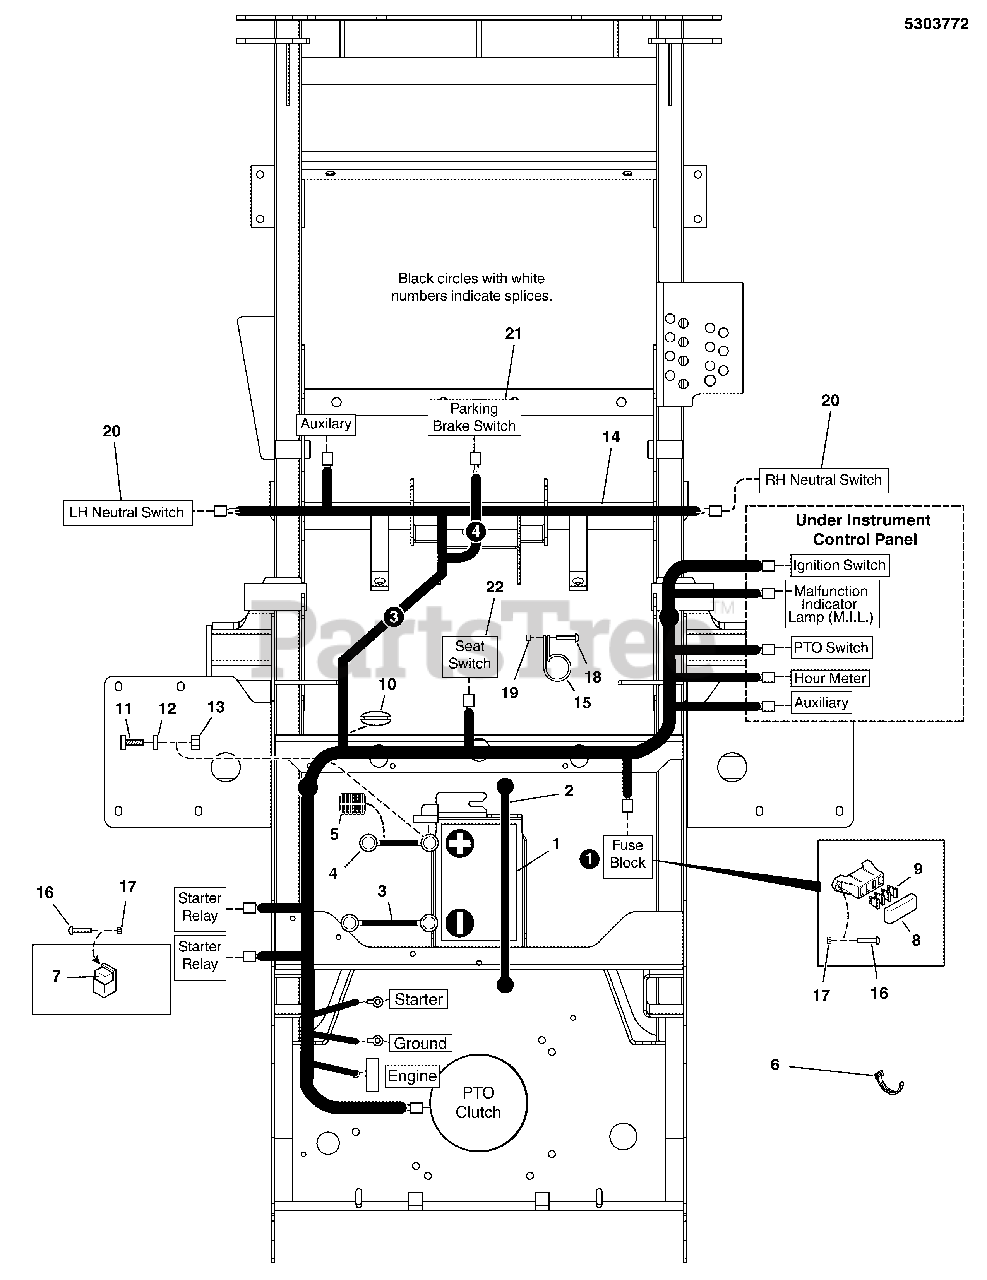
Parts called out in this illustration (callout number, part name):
1	BATTERY, WET ( BCIU1, 350 CCA)
2	STRAP-BLACK RUBB
3	BATTERY CABLE, NEG, 14, 5/16-13/32
4	BATTERY CABLE, POS, 22, 1/4-5/16
5	WIRE LOOM, 3/8 ID X 16 IN
6	TIE, SELF-LOCKING, 12"
7	RELAY, 12V, 40A
8	COVER, VINYL FUSEBLOCK
9	FUSE, ATO, 20 AMP
9	FUSE, ATO-15 (15 AMP)
10	GROMMET, 1-1/2" ID FOR 1/4" METAL
11	BOLT, 1/4-20 X 3/4 GD5 CZ
12	WASHER, 1/4 SAE
13	NUT, 1/4-20 HEX SERR. FLANGE
14	WIRE HARNESS, 28HP B&S EFI
15	CLAMP, VINYL INSULATED, 1.00
16	SCREW, #10-24 X 3/4 ROUND PHILLIPS
17	NUT, #10-24 HEX NYLON LOCK
18	SCREW,1/4-20X1,ZINC PHOS & OIL
19	NUT, 1/4-20 HEX NYLOCK FLANGE
20	SWITCH, PLUNGER, NO, SINGLE POLE SNAP-IN
21	SWITCH, LOW PROF, NC/NO
22	SWITCH, PLUNGER, N.C.
